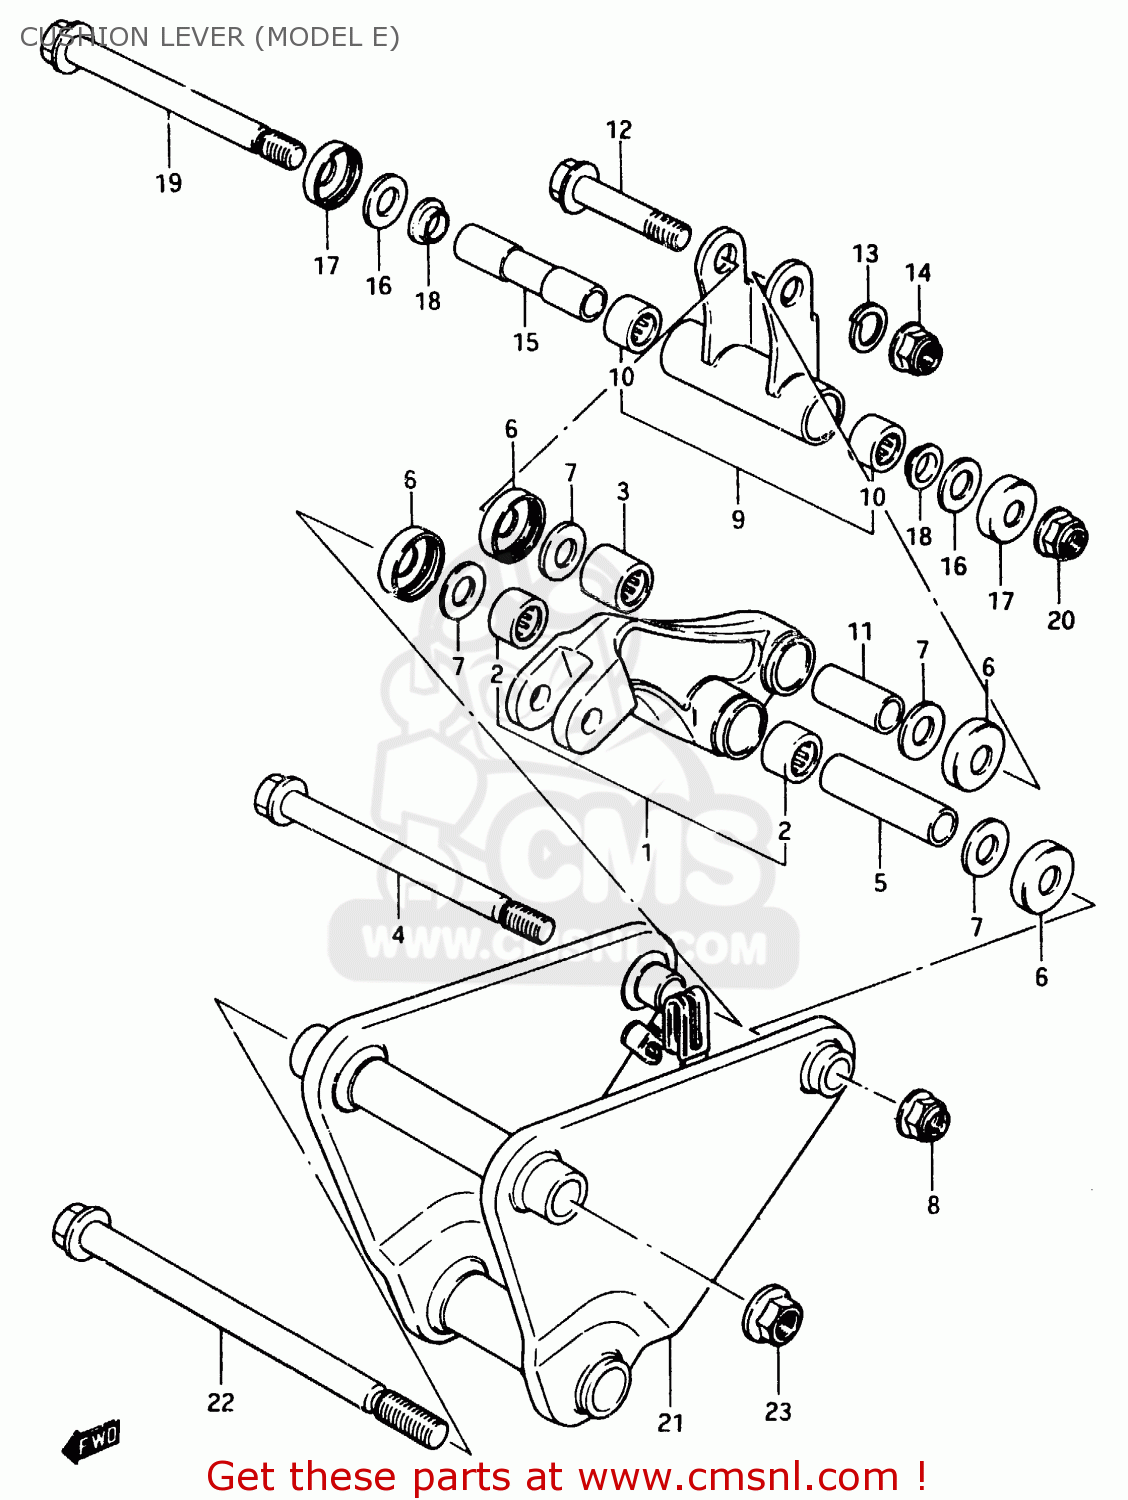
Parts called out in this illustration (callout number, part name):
1	LEVER SET,REAR CUSHION
2	ROLLER BEARING (17X24X2
3	ROLLER BEARING (17X24X25)
4	SHAFT,RR CUSHION LEVER
5	SPACER,REAR CUSHION LEVER
6	COVER,RR SWGARM DUST SEAL
7	WASHER
8	NUT 12MM
9	ROD SET,REAR CUSHION
10	ROLLER BEARING (17X24X2
11	SPACER,RR CUSHION LEVER ROD UP
12	BOLT, UPPER
13	WASHER
14	NUT
15	SPACER,RR CUSHION LVR ROD LOW
16	WASHER
17	COVER,RR SWGARM DUST SEAL
18	SPACER,REAR CUSHION ROD
19	BOLT,CUSHION ROD
20	NUT 12MM
21	BRACKET,REAR SHOCK ABSORBER
22	SHAFT,SHOCK ABSORBER BRACKET
23	NUT
